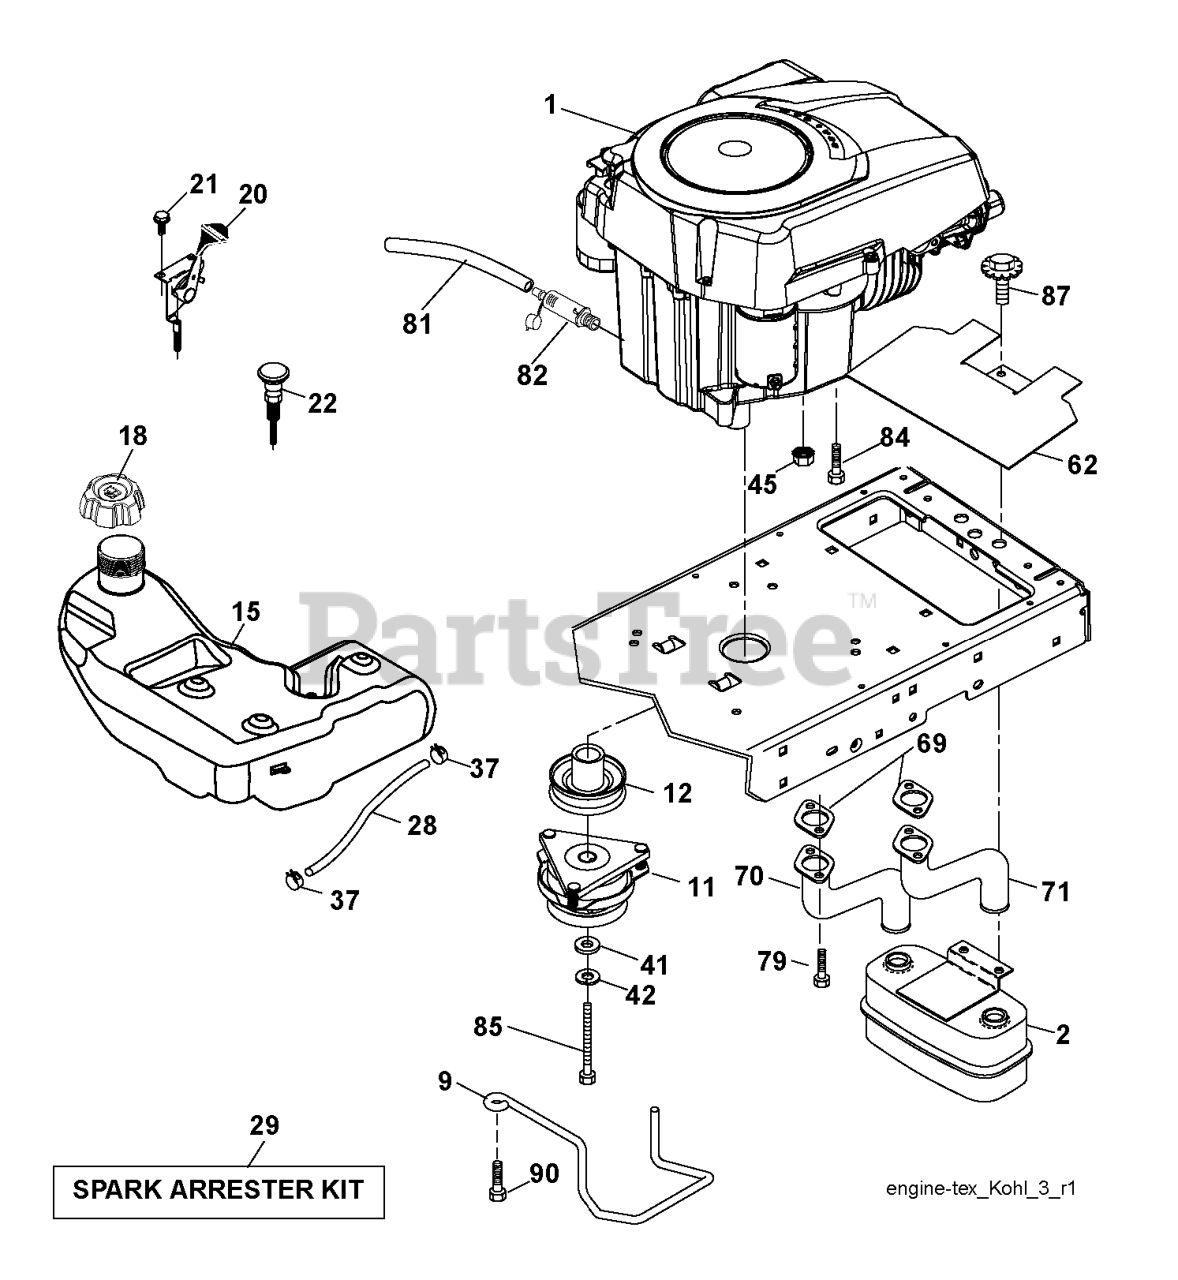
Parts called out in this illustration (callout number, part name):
2	MUFFLER.TWIN.CYL.LOW.TONE
9	KEEPER.BELT.ENGINE.4.2
11	RB.CLUTCH.OGURA.4.4.PD
12	PULLEY.ENGINE.TUFFTORQ
15	TANK.FUEL.4GAL
18	CAP.FUEL.TANK.3"GREY
20	THROTTLE CONTROL
21	SCREW.#10 X 0.750.BOS
22	CONTROL.CHOKE.ERGO.PUSH-IN.BLA
28	REPL BY 532 00 85-43
29	KIT.SPARK ARRESTOR 794945 B&S
37	HOSE CLAMP
42	LOCKWASHER
45	NUT
62	RP SHIELD HEAT MUFFLER
69	GASKET.EXHAUST.KOHL.CV18-CV26
70	RP.PIPE-EXHAUST LH
71	RP.PIPE-EXHAUST RH
79	SCREW.SOCKET HD.5/16-1
81	TUBE, DRAIN OIL ASM.
82	PLUG DRAIN OIL EASY
84	SCREW 3/8-16X1
85	BOLT HEX 7/16-20X4-1/4"
87	BOLT.5/16-18UNCX3/4 W/SEMS.BLK
90	SCREW 3/8-16X1
